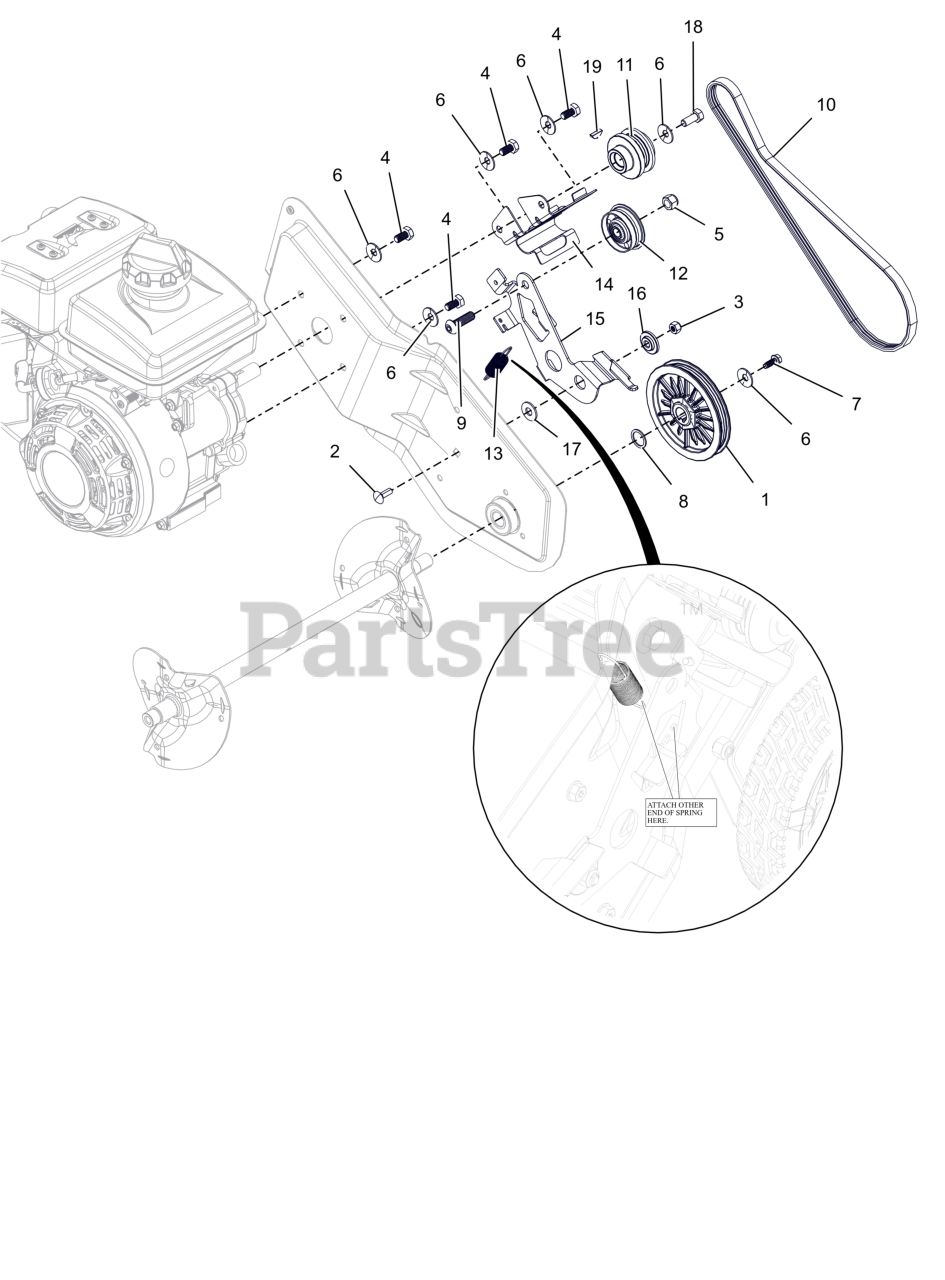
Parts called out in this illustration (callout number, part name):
1	PULLEY, ASM ROTOR
2	BLT, RDHDSQSHK .25-20X0.750 (BLACK)
3	NUT, NYLON .250 - 20 (BLACK)
4	SCR, CAP - M8X1.25 H6 THREAD
5	NUT,NYL .38-16 G5 ZCC
6	WSHR, BEVEL SPRING LOCK
7	1/4-20 X 5/8 TAPTITE
8	WSHR, THRUST
9	3/8-16X1.25 BHCS
10	V-BELT, RIBBED
11	PULLEY, ENGINE
12	PULLEY, IDLER
13	SPRG, BRAKE
14	GUIDE, BELT
15	ARM, IDLER
16	PULLEY, IDLER BUSHING
17	WSHR, FLAT .375X.875X.065 (BLACK)
18	BLT, HEX .31-24X.750 G5 ZCC
19	KEY, WDRF .157 X .630
